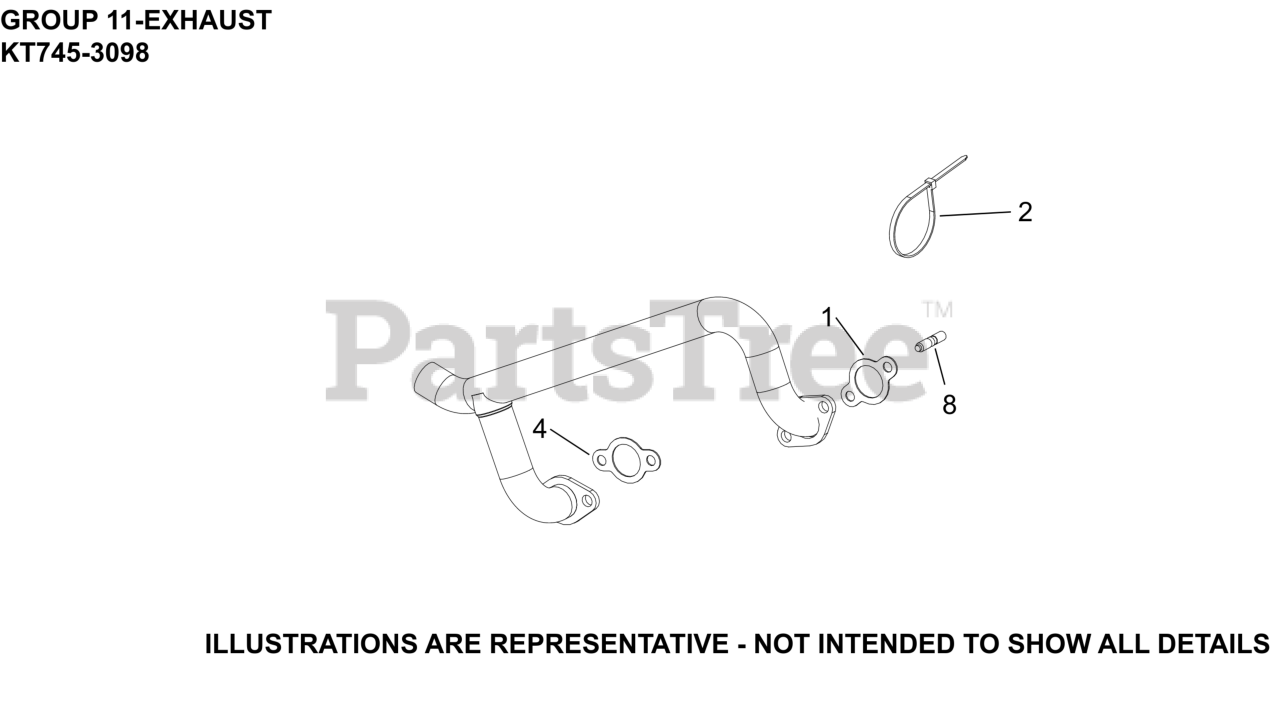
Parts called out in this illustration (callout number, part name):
1	GASKET, EXHAUST MANIFOLD
4	NUT, HEX FLANGE LOCK (M8)
8	STUD, METRIC EXHAUST
